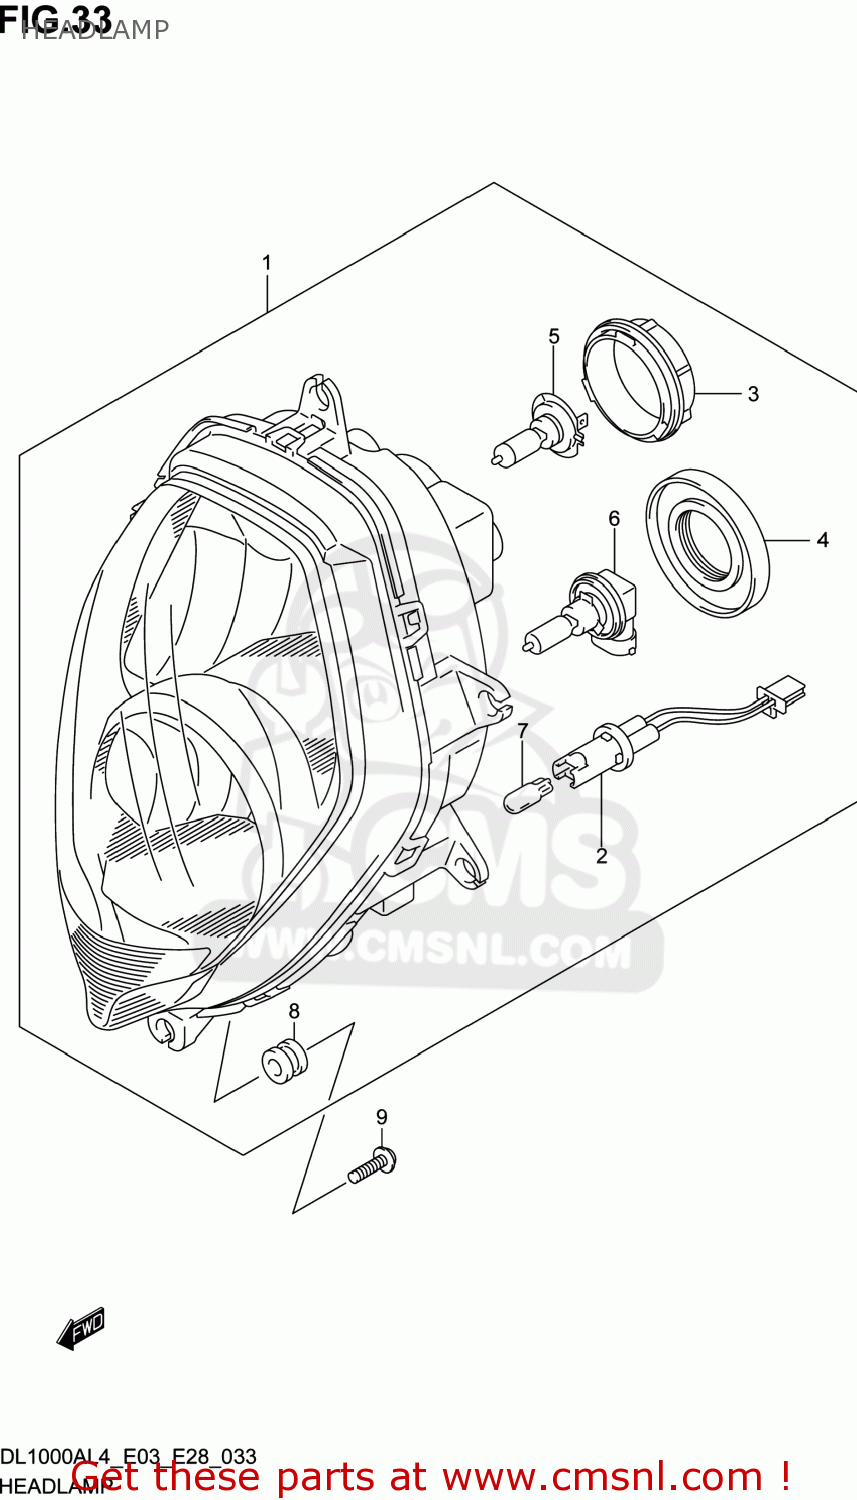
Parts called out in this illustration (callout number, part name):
1	HEADLAMP ASSY
2	CORD ASSY
3	COVER
4	SEAL COVER
5	BULB(12V55W/H7/PX26D/PHILIPS)
6	BULB(12V65W,H9)
7	BULB(12V5W)
8	CUSHION
9	SCREW(5X15)
